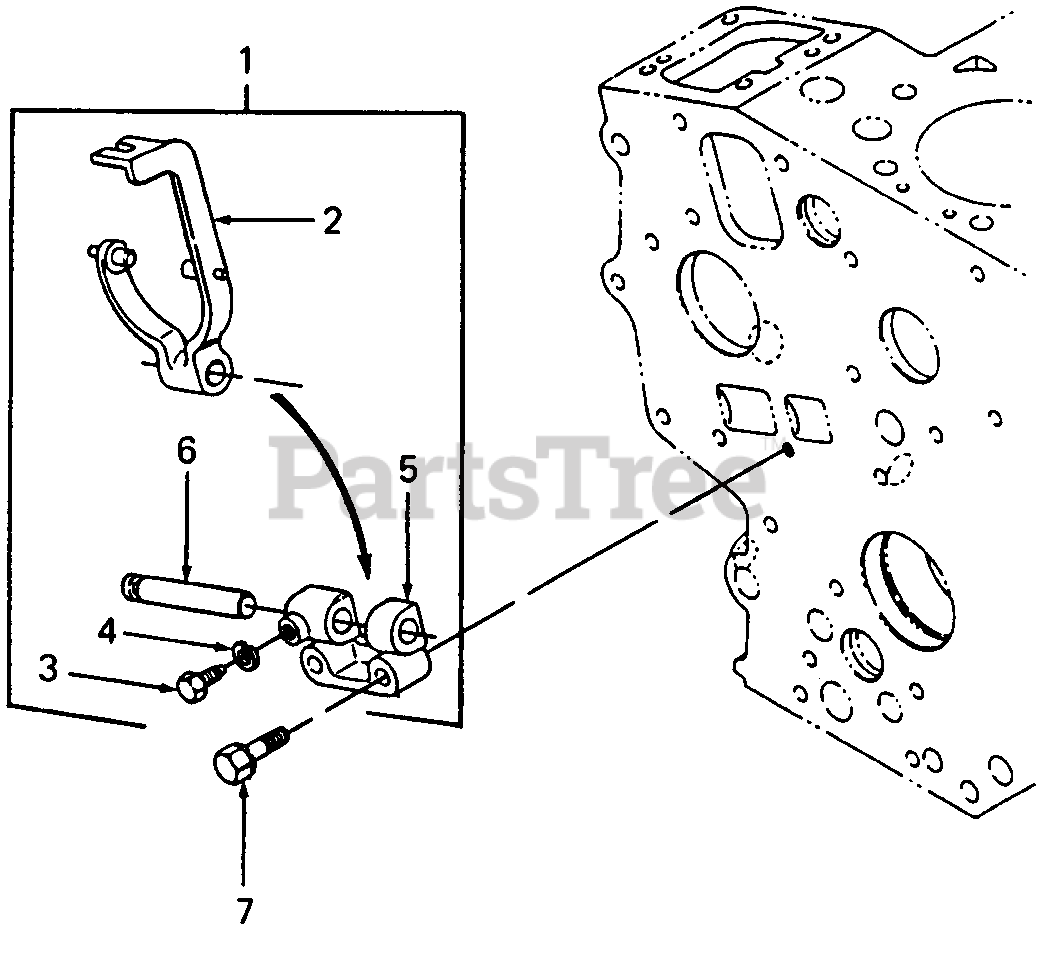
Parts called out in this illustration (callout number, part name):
1	Fork Lever Assy
4	Washer, Spring
5	Holder, Fork Lever
6	Shaft, Fork Lever
